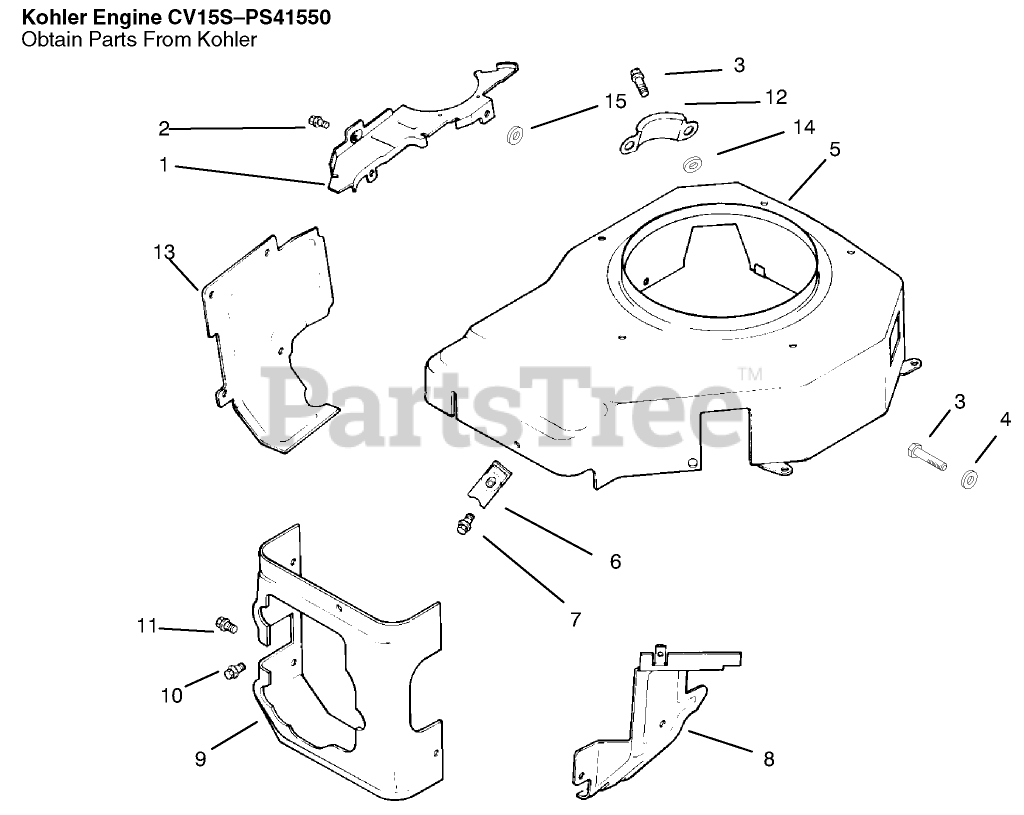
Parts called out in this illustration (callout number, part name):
1	Plate-Blower Housing (Only On: 72042,72043,72062,72063)
4	Washer
5	Housing-Blower
8	Baffle-Carburetor (Only On: 72042, 72043, 72062, 72063)
9	Baffle-Cylinder Head (Only On: 72042, 72063, 72062, 72043)
12	Cover-Pinion
13	Baffle-Cylinder Barrel (Only On: 72042, 72063, 72062, 72043)
14	Washer
